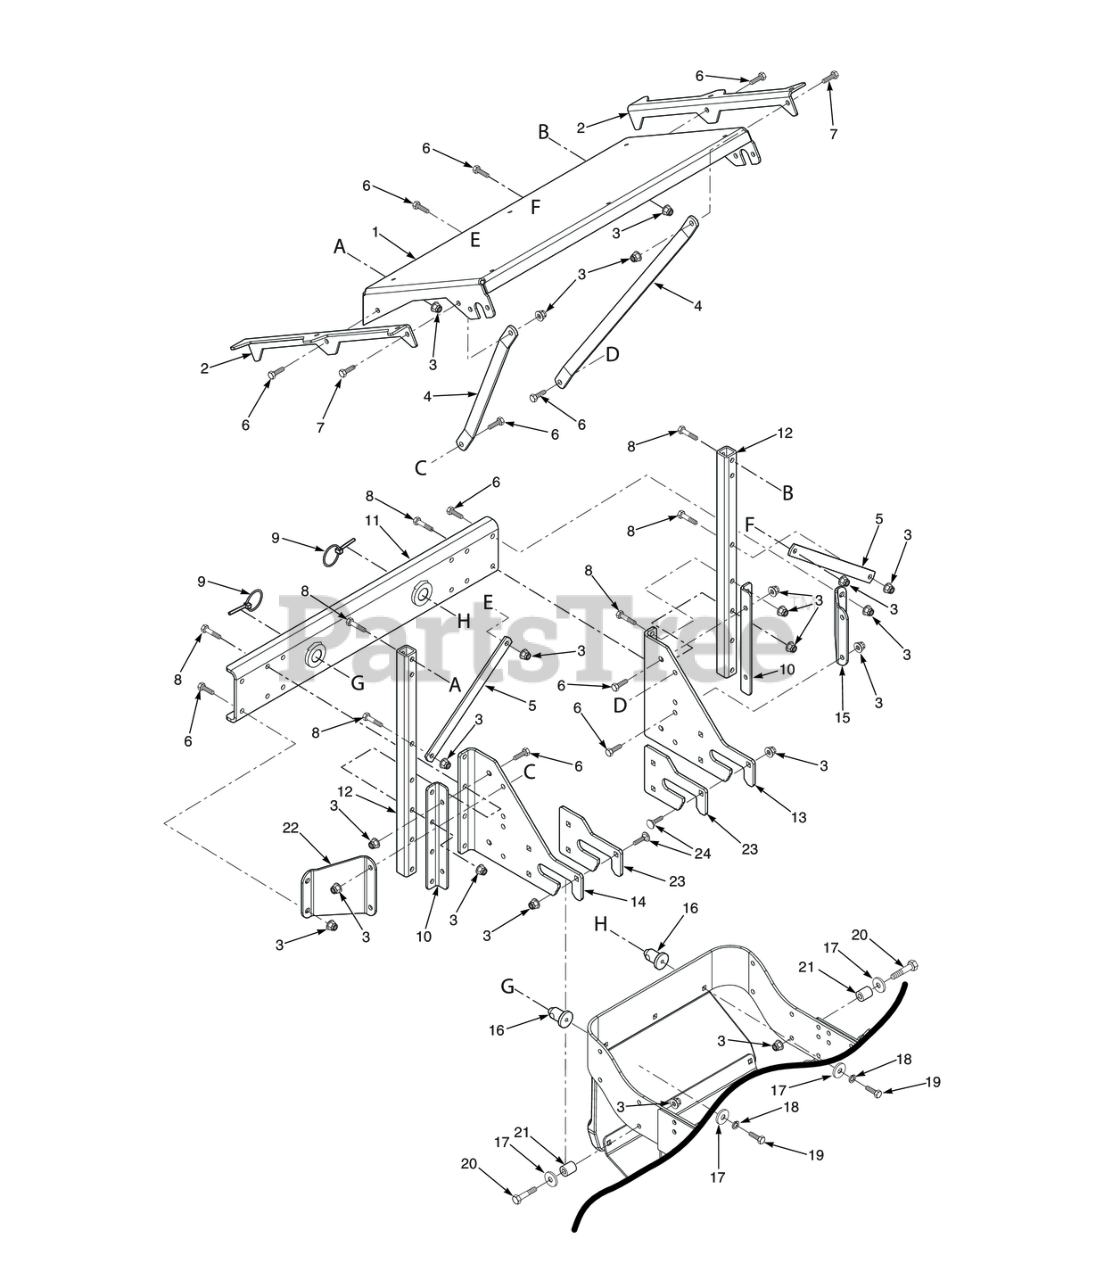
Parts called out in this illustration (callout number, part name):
1	Support Frame, Hopper
2	Bracket, Hopper Support
3	Nut, Flange Elastic Stop Nut, 3/8-16
4	Brace, Stiffener
5	Brace, Engine Mounting
6	Bolt, Hex Head, 3/8-16 x 1 Gr. 5
7	Bolt, Hex Head 3/8-16 x 1-1/4" Grade 8
8	Bolt, Hex Head 3/8-16 x 2-1/4" - 61"
9	Quick Pin, 5/16" Dia.
10	Mounting Bracket, Tube
11	Mounting Bracket Weldment
12	Tube, Upright
13	Mounting Bracket, GC R.H.
14	Mounting Bracket, GC L.H.
15	Angle Bracket, GC
16	Pin, GC Locator
17	Flatwasher, 3/8-.406 x 1-1-1/2 x 7 Gauge
18	Lockwasher, 3/8" Spring, Kawasaki FX / FS
19	Bolt, Hex Head 3/8-16 x 1-1/4" Grade 8
20	Bolt, Hex Head 3/8-16 x 2-1/4" - 61"
21	Spacer
22	Angle Bracket, GC
23	Wear Plate, GC
24	Carriage Bolt, 3/8-16 x 1-1/4"
